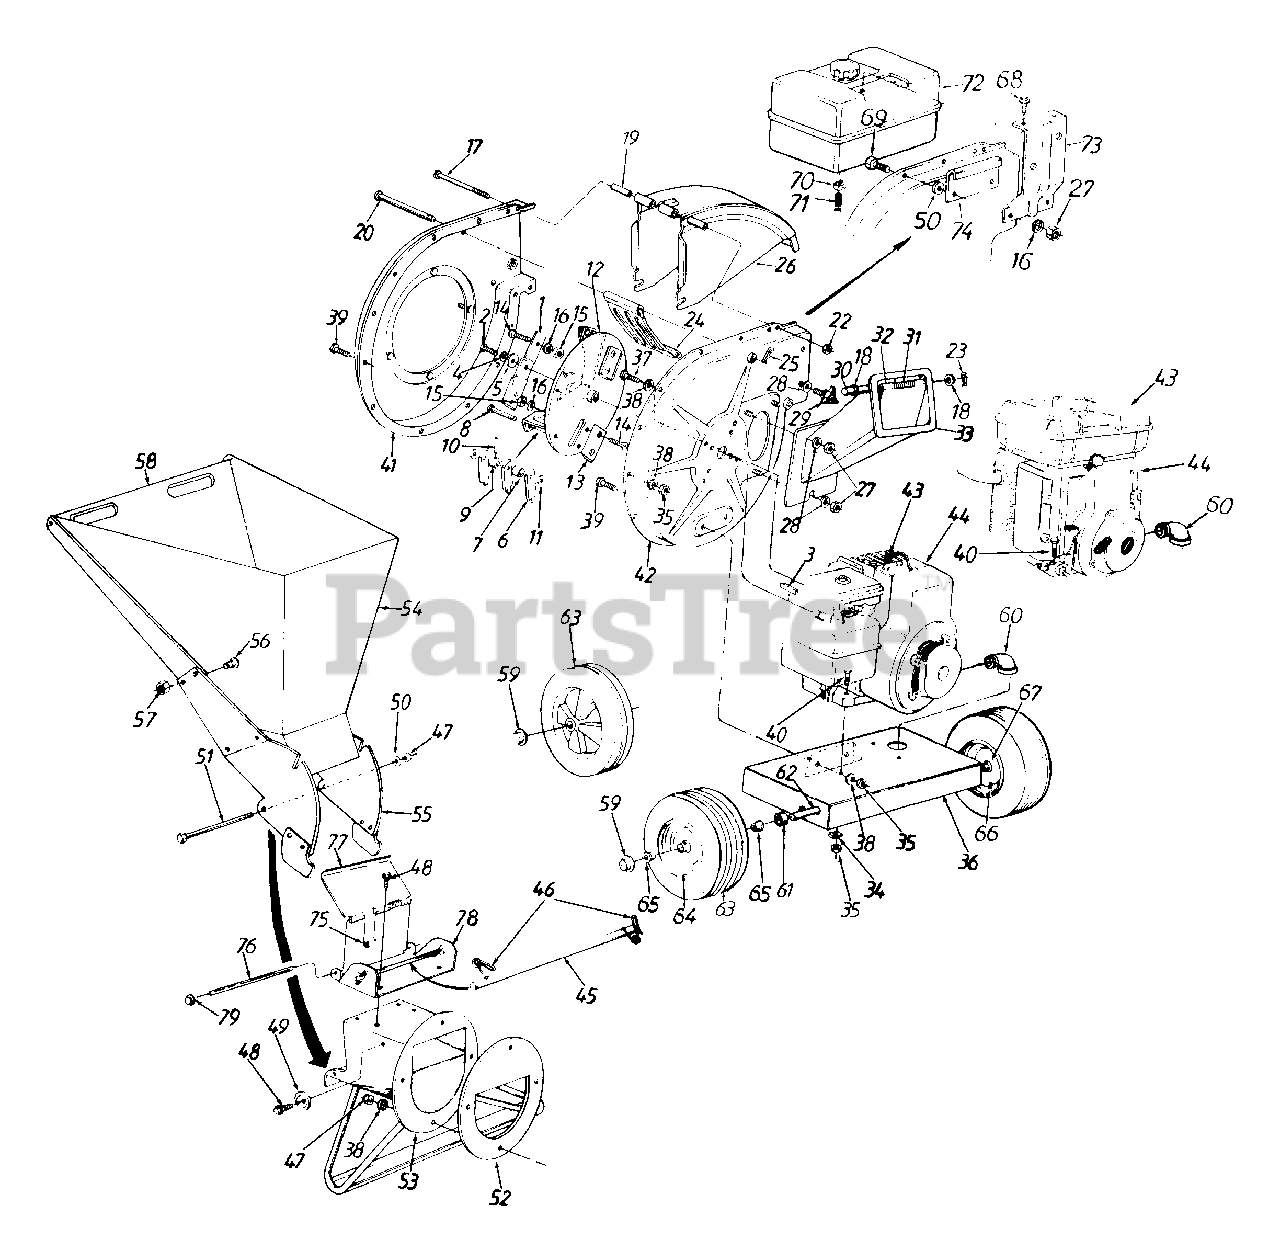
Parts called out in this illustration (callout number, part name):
1	Blade
2	Hex Patch Bolt 3/8-24 x 2" Lg. (Gr. 8)
2	Hex Patch Bolt 3/8-24 x 2.25" (Gr. 8)
3	Sq. Key 1/4 x 2.0" Lg.
4	L-Wash. 3/8" I.D. H.D.
5	Fl-Wash..406" I.D. x 1.25" O.D. Hdn.
6	Flail
7	Flail Spacer
8	Clevis Pin .496" Dia.
9	Flail Spacer w/.160" Dia. Hole
10	Spring Roll Pin 1.12" Lg.
11	Fl-Wash..531" I.D. x .94" O.D.
12	Impeller Ass'y. Comp.
13	Chipper Blade
14	Flat Hd. Scr. 5/16-24 x .75" Lg.
15	Hex Top L-Nut 5/16-24 (Gr. 5)
16	L-Wash. 5/16" I.D.
17	Hex Bolt 1/4-20 x 3.75" Lg.
18	Fl-Wash. .281" I.D. x .5" O.D.
19	Chute Hinge Spacer 1.66" Lg.
20	Clevis Pin .5" Dia. x 4.62" Lg.
22	Hex Ctr. L-Nut 1/4-20 Thd.
23	Cotter Pin
25	Internal Cotter Pin 3/8" Dia.
27	Hex Nut 5/16-18 Thd. (Gr. 5)
28	Bell-Wash. .345" I.D. x .88"
29	Hand Knob
30	Chipper Door Rod
31	Torsion Spring 1.14" Lg.
35	Hex Nut 5/16-18 Thd. (Gr. 5)
37	Hex Bolt 5/16-24 x .75" Lg.
38	L-Wash. 5/16" I.D.
39	Hex Bolt 5/16-18 x .75" Lg. (Gr. 5)
40	Hex Bolt 5/16-18 x 1.75" Lg.
44	Engine
45	Release Bar
46	Torsion Spring 1.06" Lg.
47	Elastic Lock Nut 5/16-18 Thd.
48	Hex Wash. Hd. Self-Tap Scr. 5/16-18 x .75" Lg.
49	Stop Washer
50	Fl-Wash. 5/16" I.D.
51	Hex Bolt 5/16-18 x 8.38" Lg.
57	Hex L-Nut 1/4-20 Thd.
60	Drain Elbow
61	Spacer.64" I.D. x .38" Lg.
62	Shredder Axle
63	Wheel Ass'y. Comp.
66	Air Valve
67	Grease Fltting
68	Hex Hi-Low Scr. 1/4" x .75" Lg.
69	Hex Bolt 5/16-18 x .88" Lg.
70	Hose Clamp
71	Fuel Line - 7" Lg.
72	Fuel Tank Ass'y. Comp.
76	Hopper Door Rod
